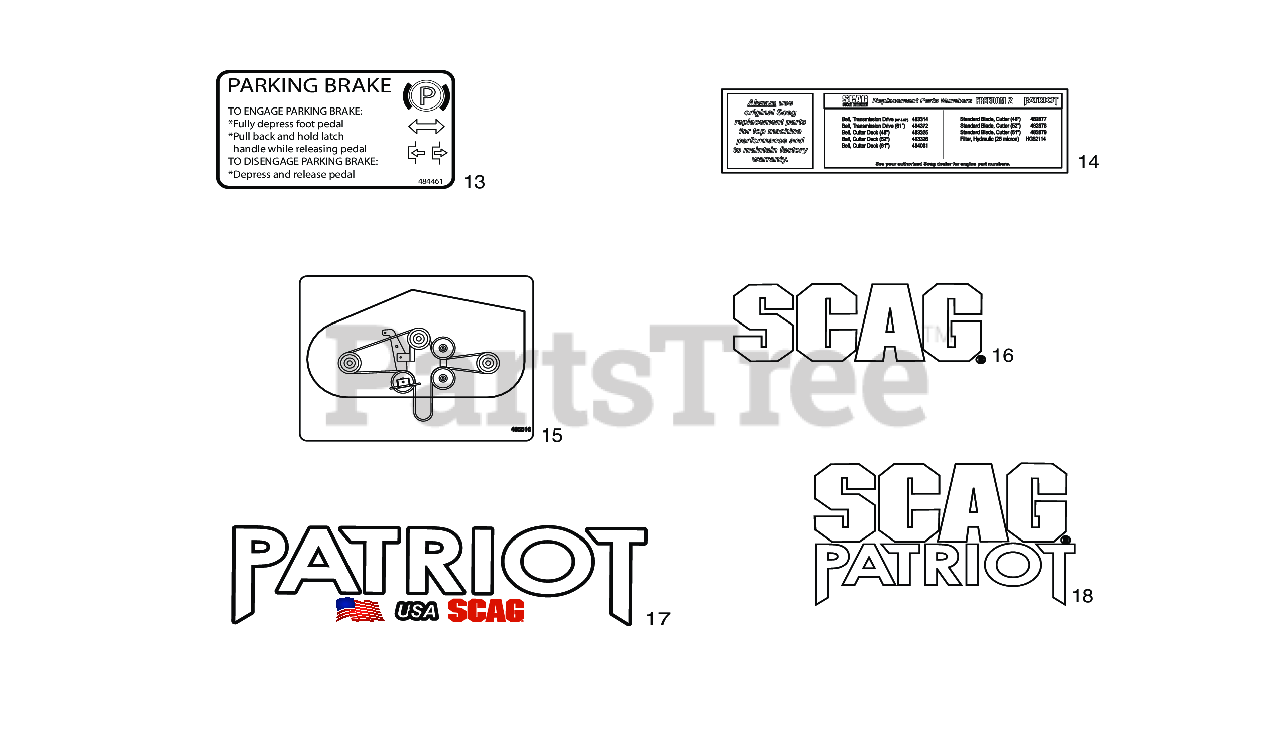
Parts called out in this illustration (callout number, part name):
13	Decal, Brake
14	Decal, SFZ / SPZ Replacement Parts
15	Decal, SZL / SFZ / SPZ Belt Routing
16	Decal, Scag - Fuel Tank
17	Decal, Patriot, (White Logo) - Fuel Tank
18	Decal, Scag Patriot, (White Logo) - Fuel Tank
